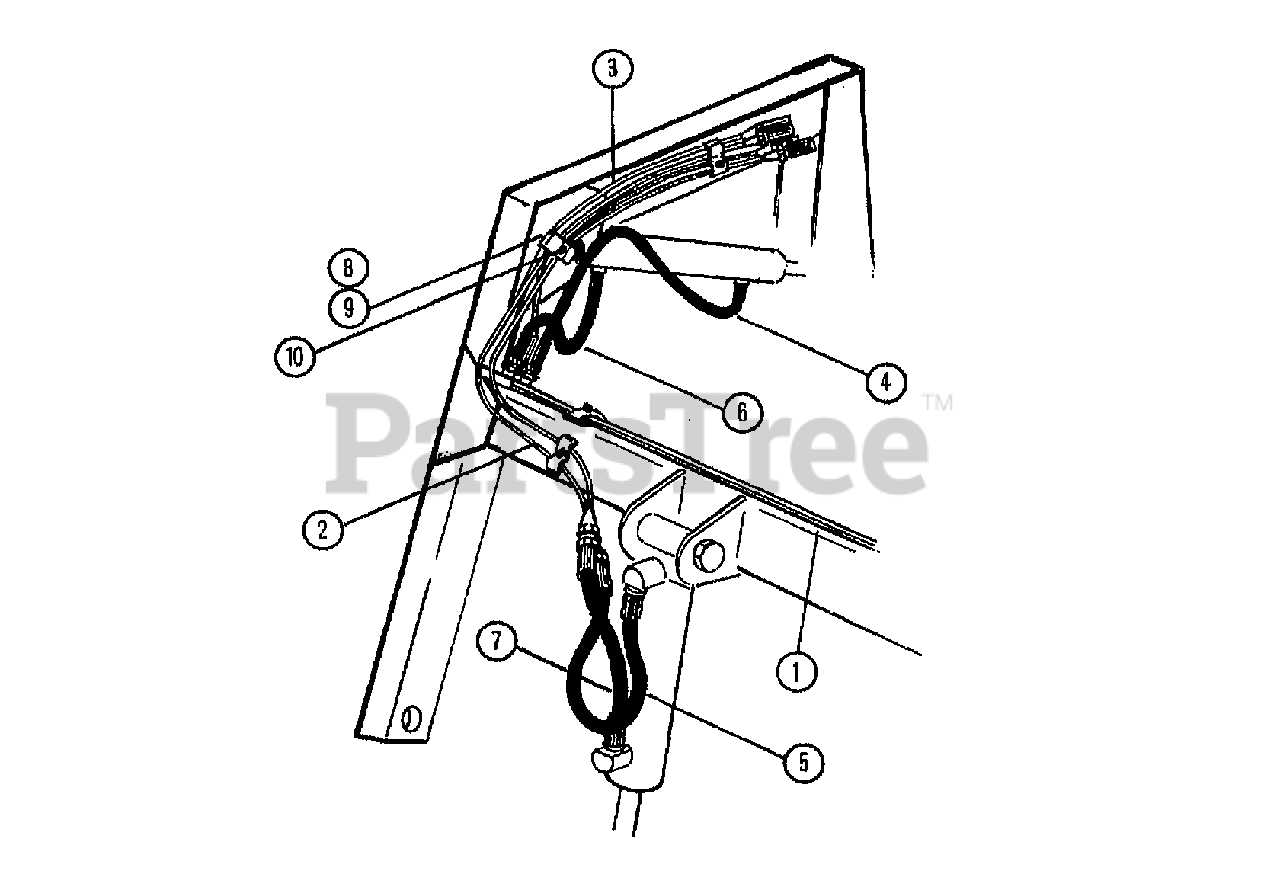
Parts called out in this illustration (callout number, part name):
1	TUBELINE-FRONT
2	TUBELINE-REAR
3	TUBELINE-REAR
6	HOSE-HYDRAULIC
8	CLIP-TUBE LINE
